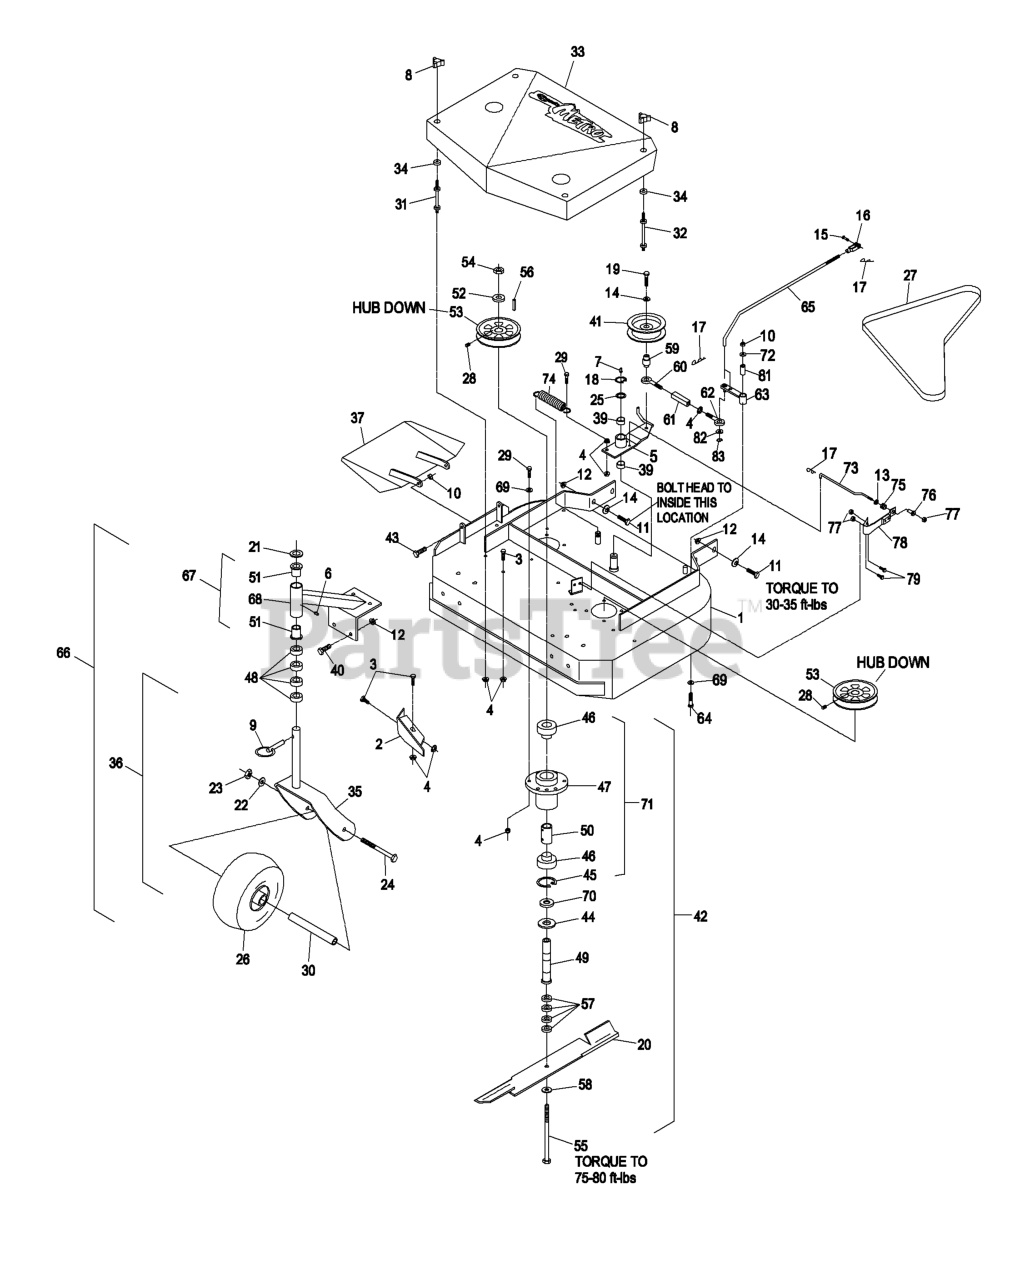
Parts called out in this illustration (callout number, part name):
2	BAFFLE-DOGLEG
3	SCREW-HH
6	FITTING-GREASE
7	FITTING-GREASE
8	KNOB-3 PRONG
10	NUT-LOCK, NI
11	SCREW-HH
12	NUT-HHF, WHIZ
13	RING-PUSH ON
14	WASHER-BELLEVILLE
15	PIN-CLEVIS
16	YOKE-ADJUSTABLE
17	PIN-COTTER
18	RING-RETAINING, EXT
19	SCREW-HH
21	WASHER-FLAT
22	WASHER-LOCK
23	NUT-HH
24	SCREW-HH
25	WASHER-SPINDLE
27	BELT,BLADE VIKING HYD 36
28	SCREW-SET
29	SCREW-HH
31	STUD-SHIELD, BELT (SHORT)
32	STUD-SHIELD, BELT (LONG)
37	WLD,CHUTE 36 RIGID
38	NUT-LOCK, NI
39	SLEEVE-BEARING
40	SCREW-HH
42	HOUSING,CUTTER COMPLETE(S
43	SCREW-HH
44	GUARD-BEARING, BOTTOM
45	RING-SNAP
46	BEARING
48	SPACER-CASTER
49	TUBE-SPINDLE, SHORT
50	SPACER-BEARING
51	BEARING-FLANGED
52	WASHER-RETAINER, SHEAVE
53	SHEAVE
54	NUT-HEX
55	SCREW-CAP, HH
58	WASHER-SPRING
59	BUSHING-ENGAGEMENT
60	EYEBOLT-THREAD, LH
61	BODY-TURNBUCKLE
62	EYEBOLT-THREAD, RH
63	ARM-ASSIST, 32/36
64	SCREW-HH
65	ARM-ASSIST, LINKAGE
66	CASTER/MOUNT ASM
67	SUPPORT ASM
69	WASHER-SPRING
70	SPACER-PULLEY/BEARING
72	WASHER-FLAT
73	ROD-BRAKE
74	SPRING-EXTENSION
75	SPRING-COMPRESSION
76	SPACER-FLANGED
77	NUT-LOCK, NI
78	PAD AND SPRING ASM
79	SCREW-HH
81	TUBE-PIVOT
82	WASHER-PLAIN
83	RING-RETAINING, EXT
